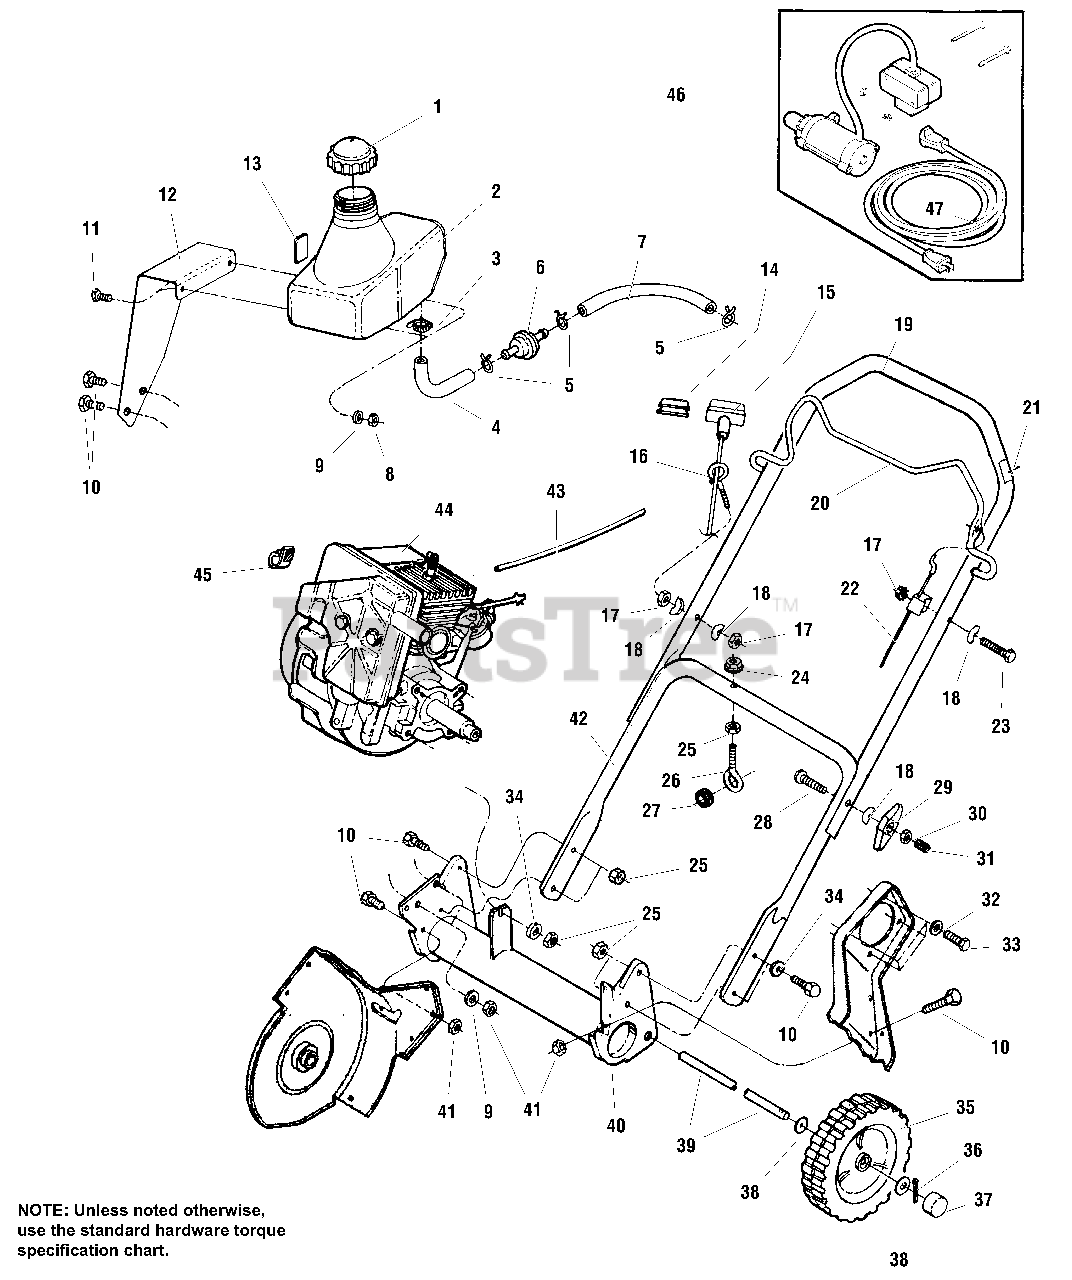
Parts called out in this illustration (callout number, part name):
3	CLAMP, Worm drive
4	HOSE, Fuel, 3-1/4" Long
5	CLAMP, Wire form
6	FILTER, Gas
7	HOSE, Fuel, 8" Long
8	NUT, Nylock, 1/4-20
9	WASHER, Flat 1/4
10	BOLT, Hex, 5/16-18 x 3/4
11	BOLT, Hex, 1/4-20 x 3/4
12	BRACKET, Fuel Tank
13	PAD, Rubber
14	INSERT, Metal Handle
15	HANDLE, Starter Rope
16	GUIDE, Rope
17	NUT, Keps, 1/4 - 20
18	WASHER, Curved, 5/16
19	HANDLE, Upper
20	BAIL, Auger Control
21	DECAL, Auger Control
22	CABLE, Auger Control
23	BOLT, Hex 1/4-20 x 2
24	NUT, Flange Lock, 3/8-16
25	NUT, Hex, 3/8-16
26	EYEBOLT, Chute Rotater
27	GROMMET, Eyebolt
28	BOLT, Curved Head, 5/16-18 x 2-1/4
29	KNOB, Wing
30	NUT, 5/16 - 18
31	CAP, Plastic Bolt
32	WASHER, Lock 5/16
33	BOLT, Hex, 5/16-24 x 5/8
34	WASHER, Flat, 5/16 (Left side only)
35	WHEEL & TIRE
36	PIN, Cotter, 1/8 x 3/4
38	WASHER, Flat
39	SHAFT, Axle
40	FRAME, Tube
41	NUT, Nylock, 5/16-18
42	HANDLE, Lower
43	HOSE, Fuel Primer, 8" Long
44	ENGINE, Two Cycle, 5 HP
45	CLIP, Retainer
46	KIT, Electric Start
